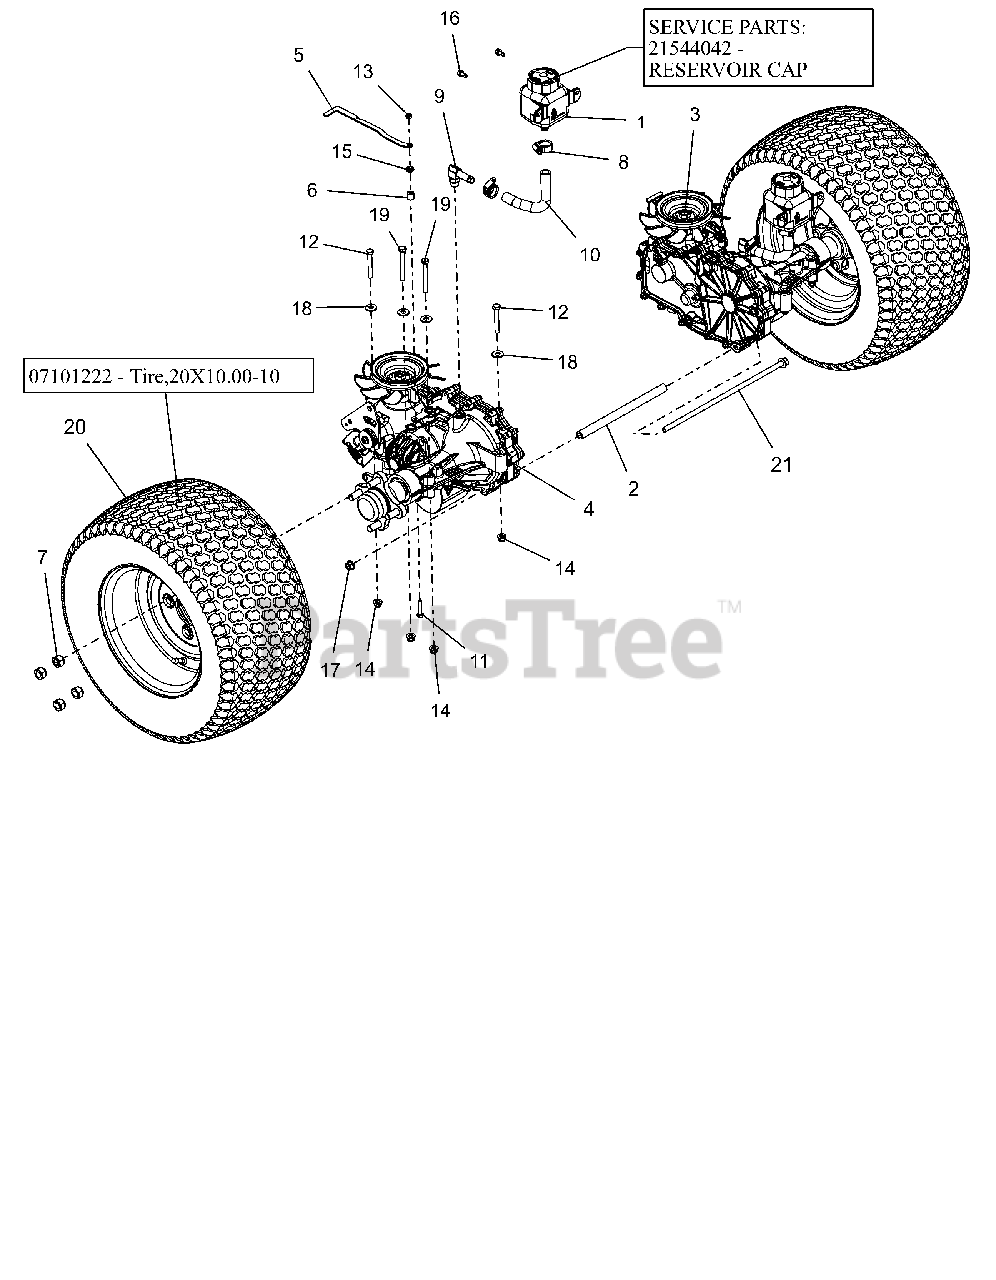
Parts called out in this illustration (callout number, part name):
1	TANK, EXPANSION
1	CAP, HYDRO RESERVOIR REPLAC.
2	SPCR, TRANSAXLE .406 ID X .630 OD X 9.27 (BLACK)
3	TRANSAXLE,ZT2800 LH
4	TRANSAXLE,ZT2800 RH
5	BRKT, DUMP VALVE
6	BSHG-SLV .265X.500X.500
7	WHEEL NUT .500-20 YZ
8	CLAMP,.88 DIA. HOSE
9	FITTING, HYD (90 DEG)
10	HOSE, FORMED LH XL
11	@BLT-HEX .25-20X1.25 GR5 YWZC
12	@BLT-HEX .31-18X2.25 GR5 YWZC
13	NUT-LK-CTR JAM .25-20 YWZC
14	@NUT-LK-NYL-FLG .31-18 YWZC
15	@NUT-SPNLK-FLG .25-20 YWZC
16	SCR-TAP .25-20X.50 HWH TR YWZ
17	NUT-LK-CTR-FLG .375-16 GF ZCC
18	@WSHR-FL-STL.38X.875X.083 YWZC
19	@BLT-HEX .31-18X2.75 GR5 YWZC
20	ASM, WHL/TIRE 20X10.00-10
20	TIRE, 20X10.00-10 (OTR)
21	BLT, HEX-FLG 0.375-16X13 GR5 ZC120
